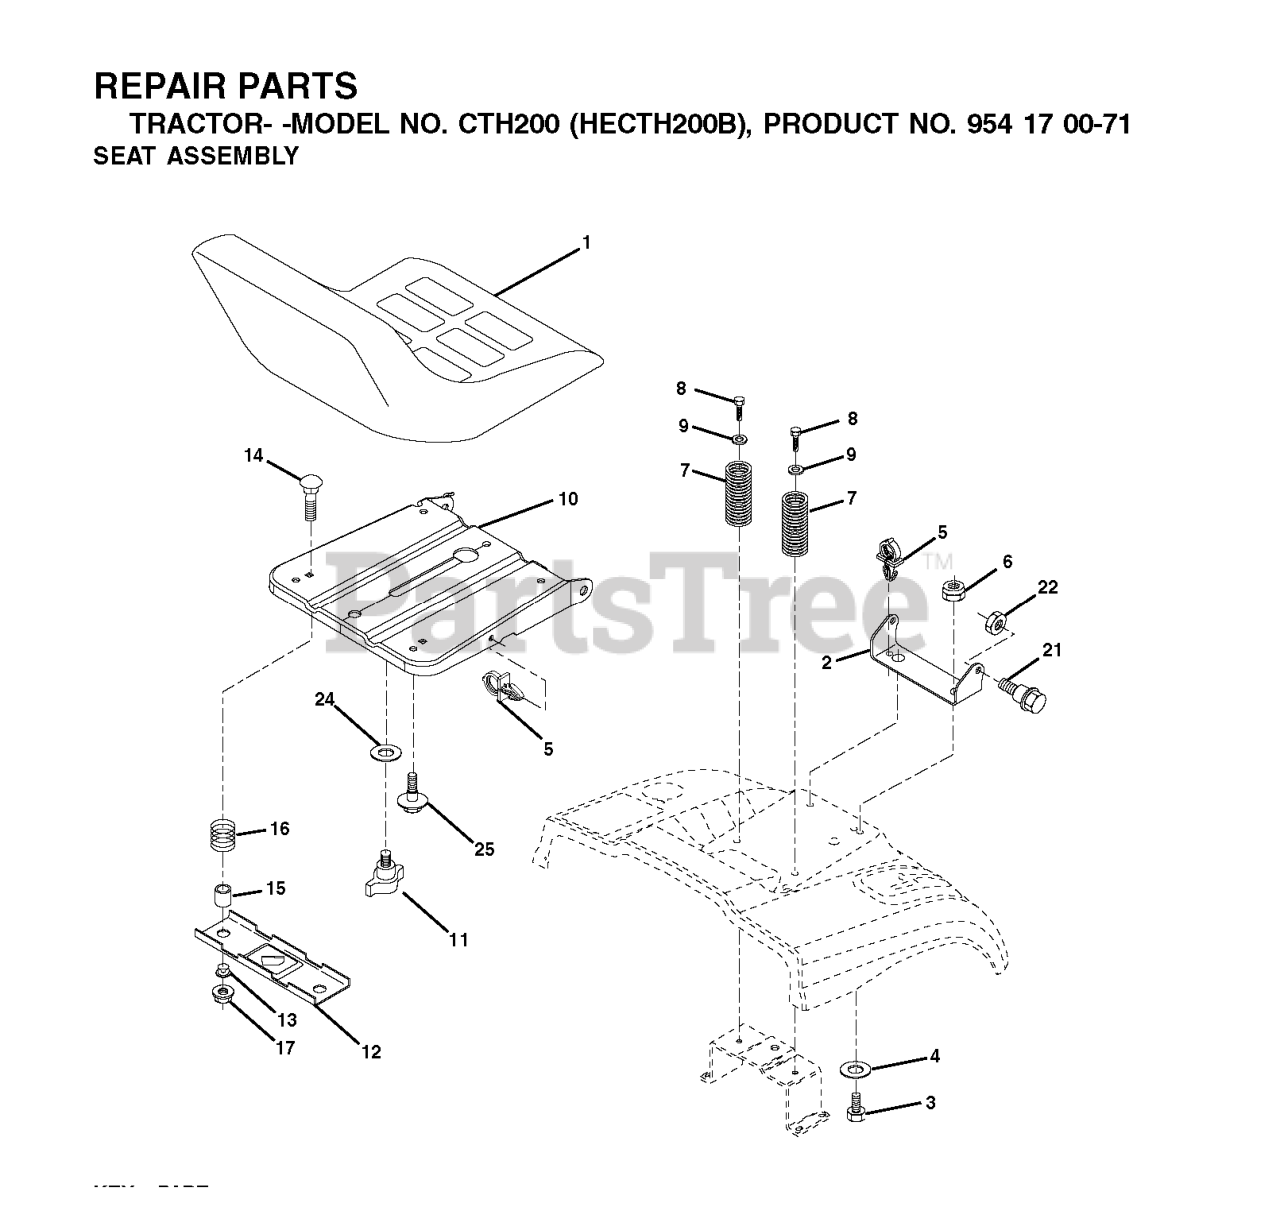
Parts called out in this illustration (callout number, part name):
1	SEAT, GRAY
2	SEAT PIVOT BRKT
3	BOLT, HEX 3/8-16X1
6	NUT
7	SPRING COMPRESSION
8	SCREW 3/8-16X1
9	WASHER
10	PAN, SEAT
11	KNOB.SEAT.ADJ.WINGNUT
12	BRKT SWITCH
14	BOLT.ROUND.HEAD.SQUARE.NECK
15	SPACER SPLIT
16	SPRING COMPRESSED
17	NUT T
21	BOLT.SHOULDER.5/16-18
22	NUT.71038.31-18.HEX.NYLOCK
25	BOLT,SHOULD
